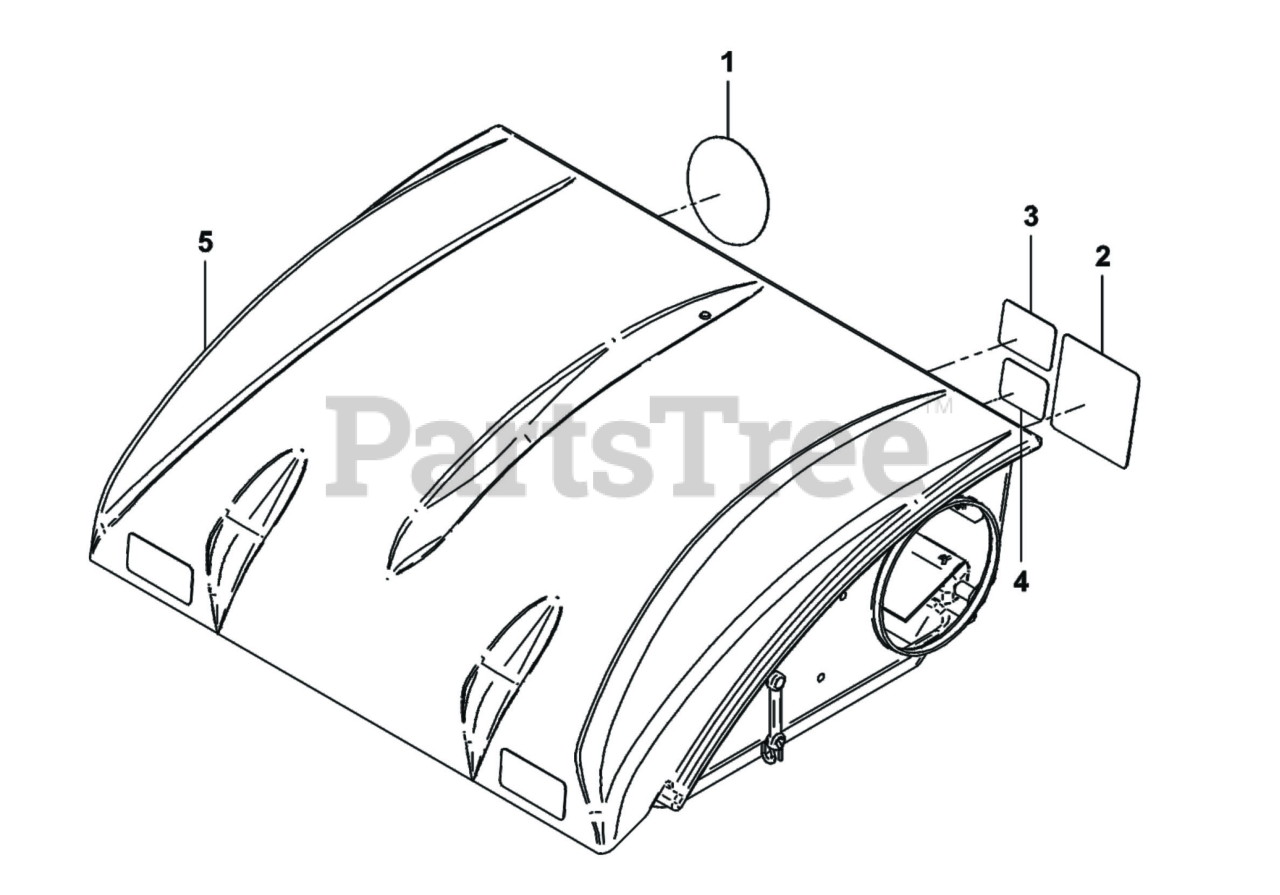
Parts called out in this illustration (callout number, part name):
1	BUILT IN USA LABEL
2	LABEL-WARNING
3	DECAL-TUBE WEAR
4	DECAL-WARNING
5	TOP ASSEMBLY W/CUB LOGO
5	TOP ASSY/P2B+ GEN2/STD MODEL
